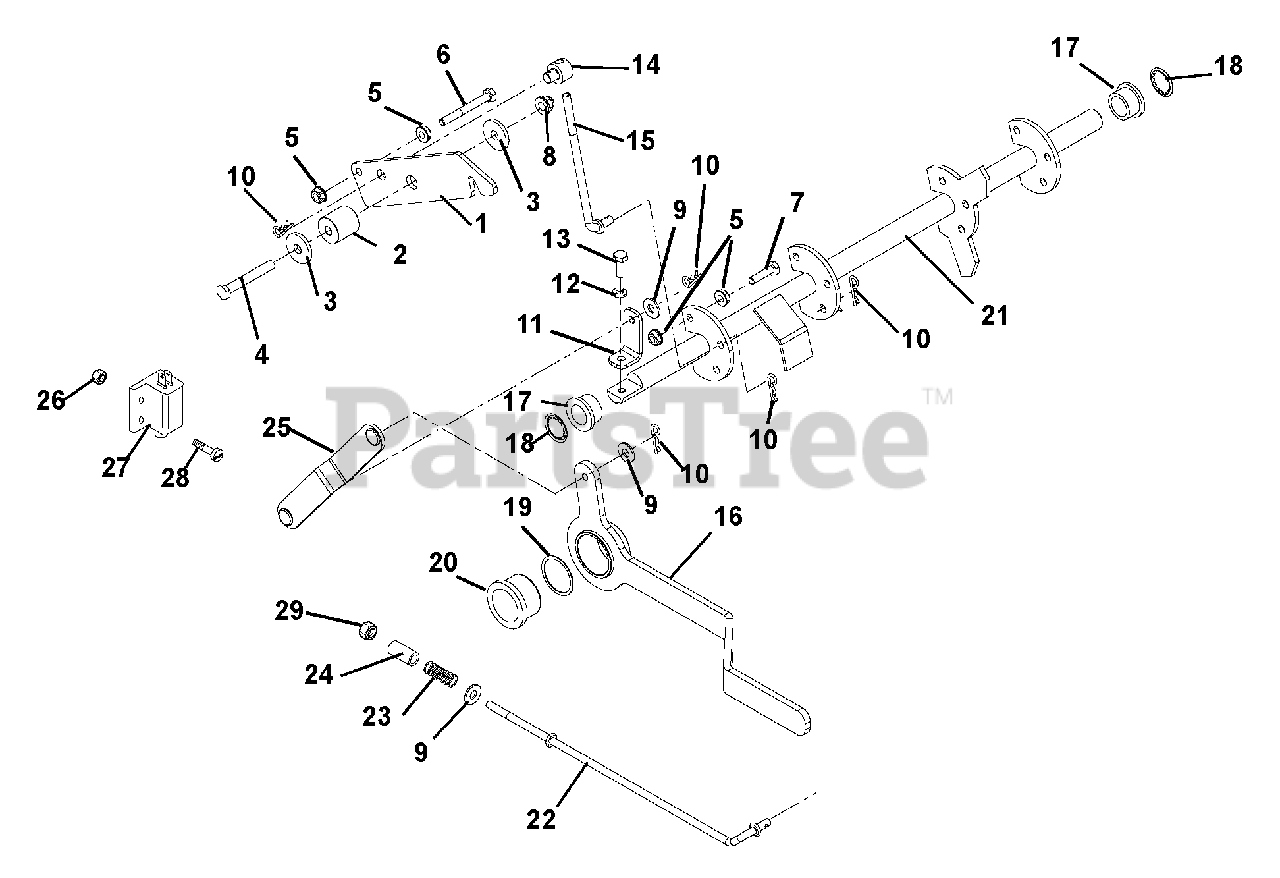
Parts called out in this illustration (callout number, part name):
1	Latch, Neutral
3	Washer, Flat Steel .344 x 1.125 x .135
4	Bolt, Hex .31-18 x 2.25 Grade 5
5	Nut, Locking Flange .250-20
6	Bolt, Hex .25-20 x 2.25 Grade 5
7	Bolt, Hex .25-20 x 1.00 Grade 5
8	Nut, Flange Nyloc 5/16-18
9	Washer, Flat Steel .312 X .734 X .065
10	Pin, Hair Int .08 x .18 x 1.18
11	Crank, Parking Brake
12	Washer, Locking .25 x .062 Regular
13	Bolt, Hex .25-20 x .75 Grade 5
14	Trunnion, Brake
15	Brake, Link
16	Lever, Park Brake
17	Bushing, Flanged .750 x 1.000 x .625 x 1.250
18	Push Nut, .745 Shaft
19	Washer, Nylon
20	Bushing, Parking Break
21	Weldment, Brake Shaft
22	Brake Link
23	Spring, Compression .045 x .50 x 1.187
25	Link, Parking Break
26	Nut, Locking Nylon 10-24 with Insert
27	Switch, Double Pole
28	Screw, Machine 10-24 x .75
29	Nut, Locking-Nylon .250-20
